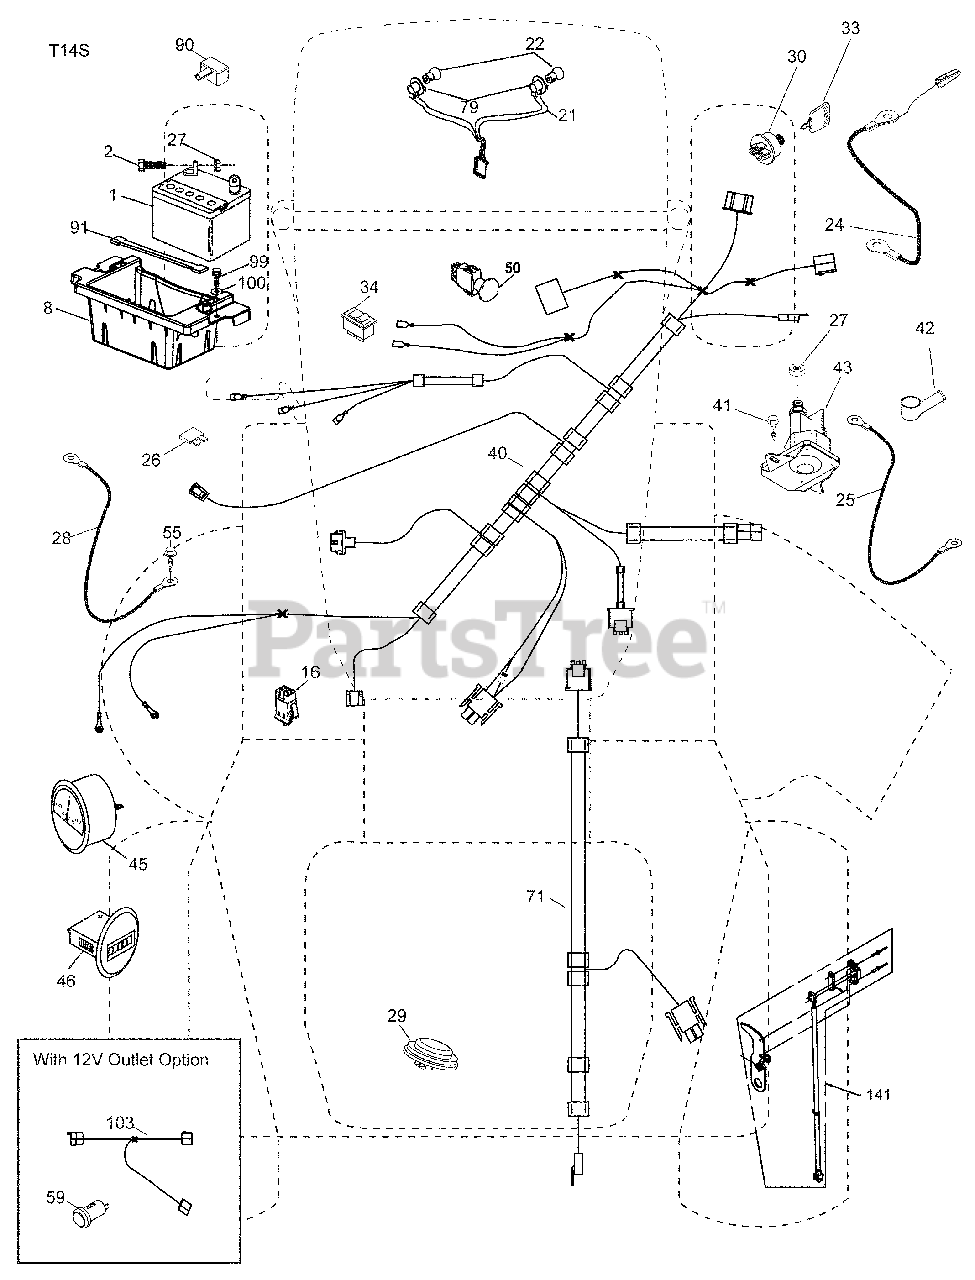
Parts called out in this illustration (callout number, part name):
1	Battery
2	Bolt Hex Head 1/4-20 x 3/4
8	Tray Battery
16	Switch Interlock Push-In
21	Harness Socket Light W/4152J
22	Bulb Light
24	Cable Battery
25	Cable Starter
27	Nut Keps Hex 1/4-20 unc
28	Cable, Ground
29	Switch, Seat
30	Switch, Ign
34	Switch Light / Reset
40	Harness Ign. Dash
41	Screw Thd Cut 1/4-20 x 1/2
42	Cover, Terminal
43	Solenoid
45	Ammeter Gauge Round
46	Gauge Servicereminder Hrmtr
50	Switch PTO
55	Screw Thdrol 5/16-18 x 3/4 TYTT
59	Outlet 12-Volt
71	Harness Ign.
79	Socket Asm Bulb Twistlock
90	Cover Terminal
91	Strap Battery Mount
99	Screw Hexwsh Thdrol 1/4-20 x 3/4
100	Washer 9/32 x 7/8 x 16 Ga.
103	Harness 12-Volt Pigtail
